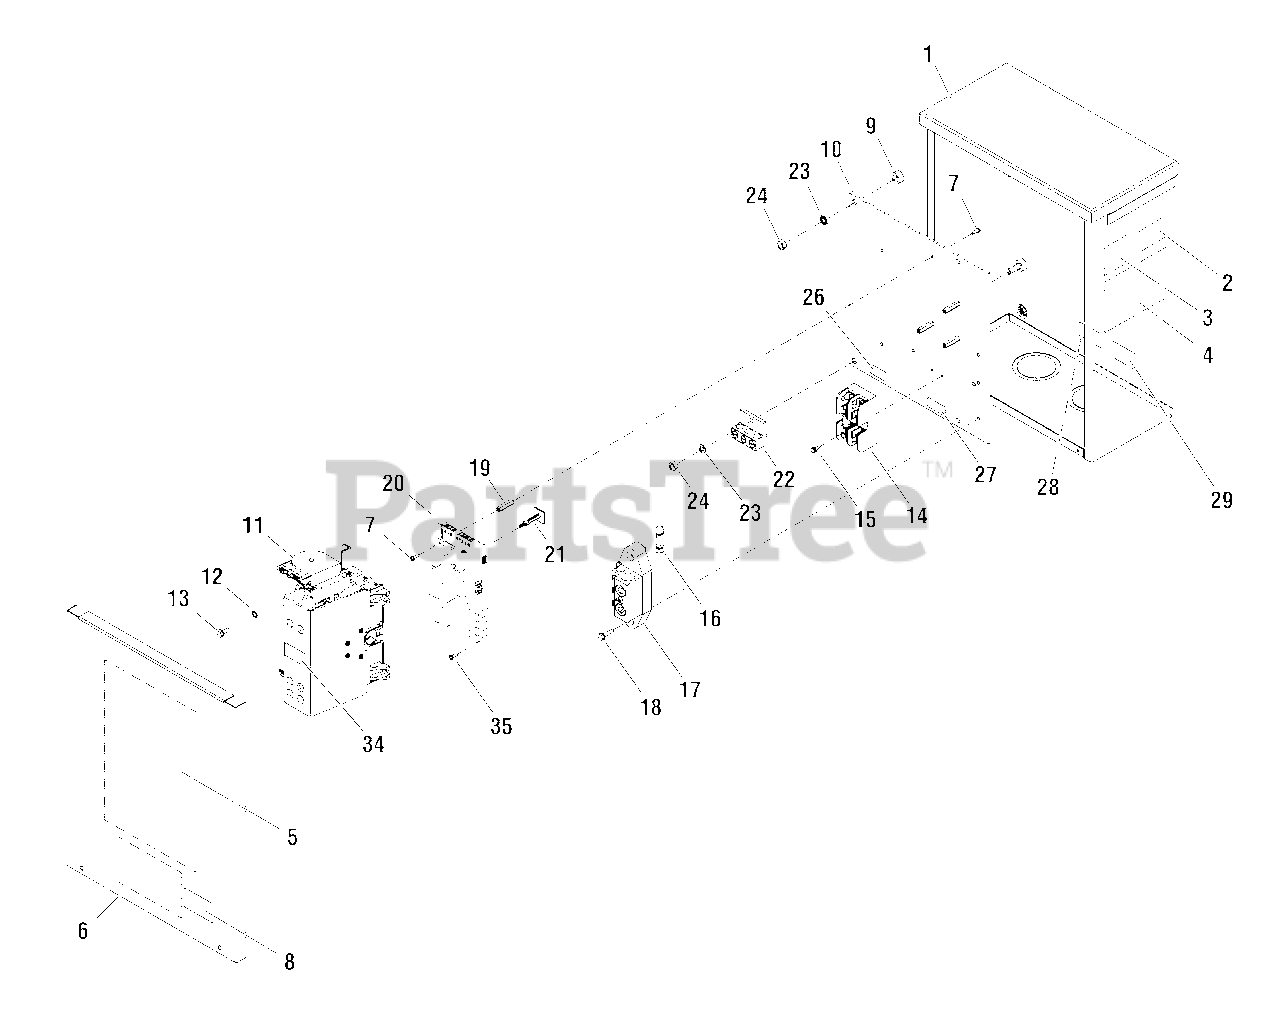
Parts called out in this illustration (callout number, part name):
1	ENCLOSURE
2	DECAL
3	DECAL
7	* SCREW, 6-32 x 3/8
9	SPACER
10	BACK PANEL
11	SWITCH, Transfer
12	* WASHER, Ext. #10
13	* SCREW, Trilobular, 10-32 x 1/2
15	* SCREW, Trilobular, 6-32 x 3/8
18	* SCREW, Trilobular, 6-32 x 3/4
20	BOARD, Circuit
22	LUG
23	* WASHER, Lock, 1/4
24	* NUT, 1/4-20
26	DECAL
27	DECAL
29	DECAL
34	DECAL
35	* SCREW, Trilobular, 6-32 x 5/8
